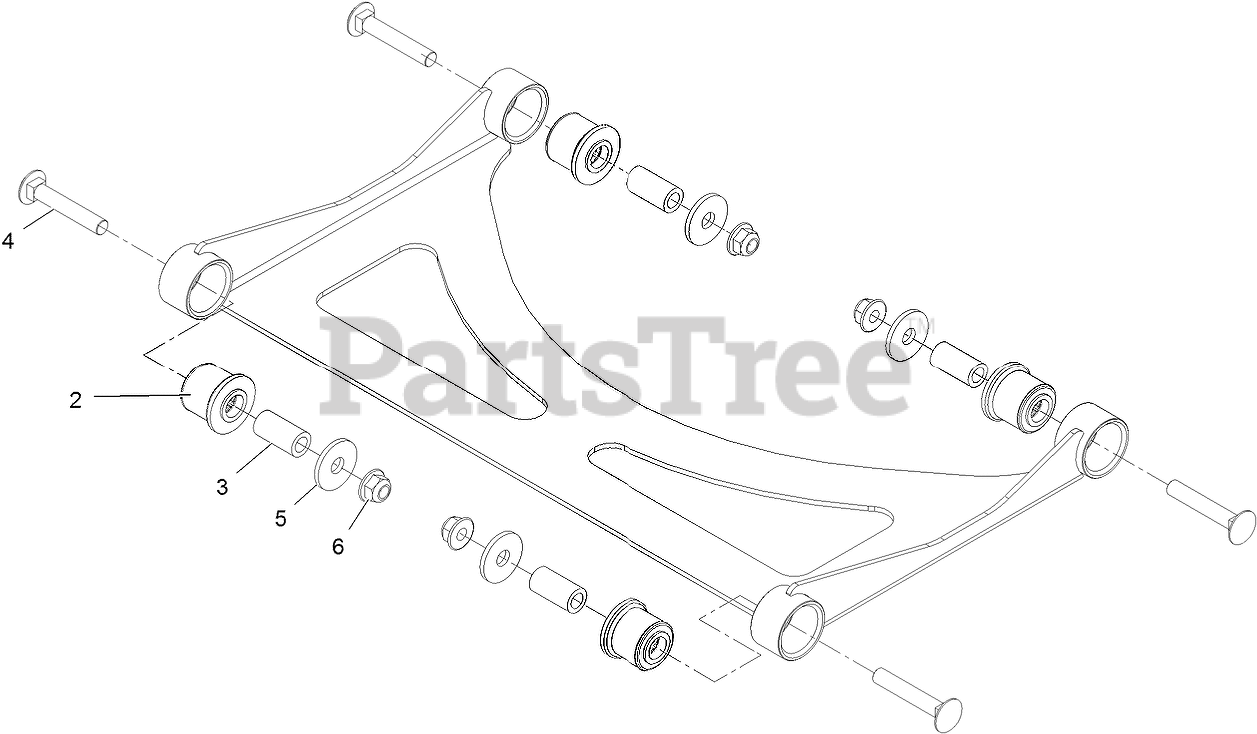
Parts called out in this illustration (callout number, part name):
2	BUSHING-RUBBER
4	Bolt-Carriage 3/8-16 X 2 1/4
5	WASHER
6	NUT-HF, NI
